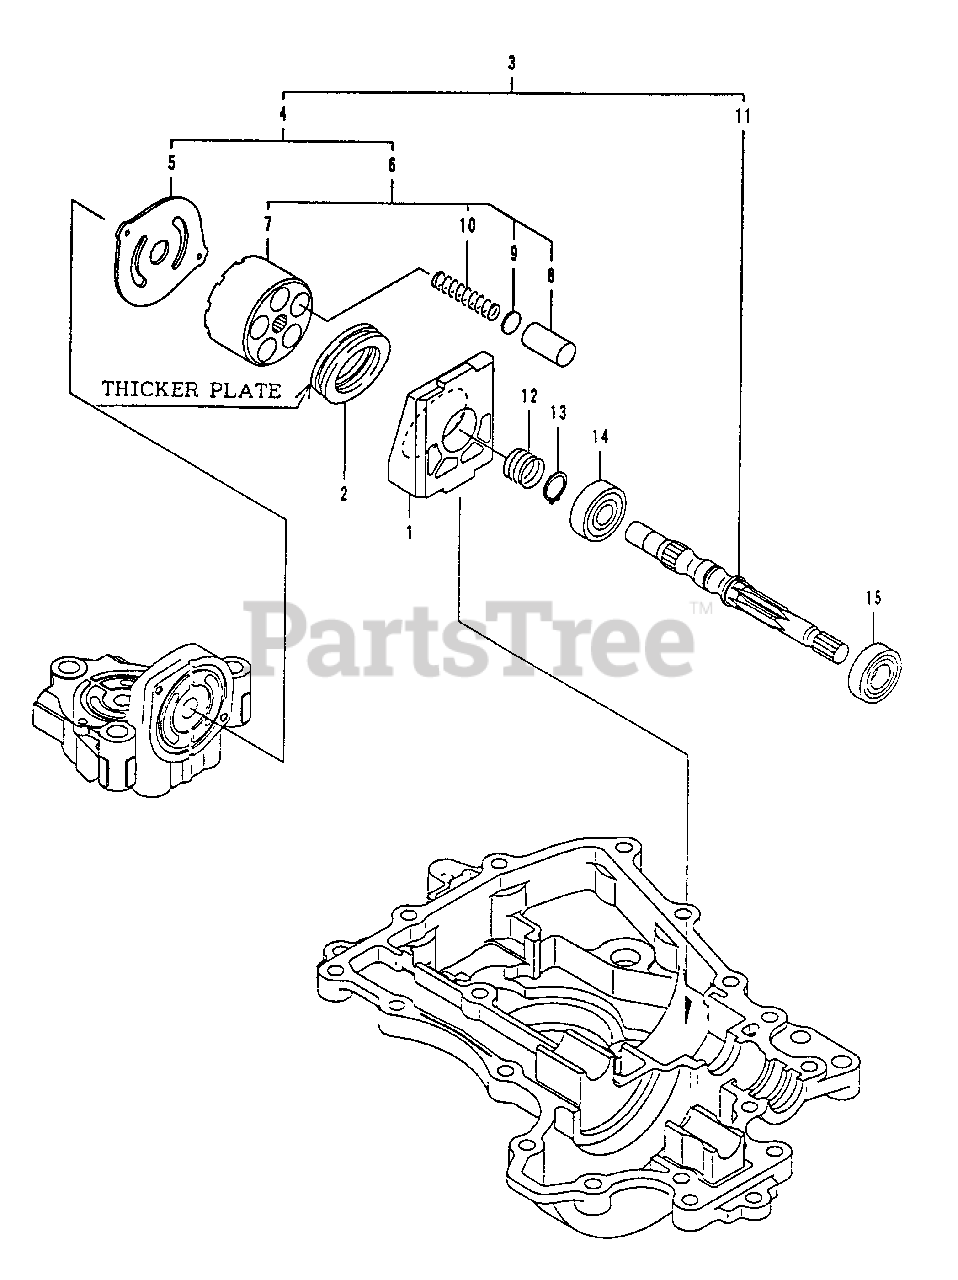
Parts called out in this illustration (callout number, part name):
2	BEARING 51106
3	MOTOR SHAFT SET
4	CYLINDER BLOCK M COMP.
5	PLATE(MOTOR
6	CYLINDER BLOCK COMP.SET
7	CYLINDER BLOCK
8	PISTON
9	WASHER 11
10	SPRING (PISTON
11	MOTOR SHAFT
14	BALL BEARING 6002
15	BALL BEARING 6201
